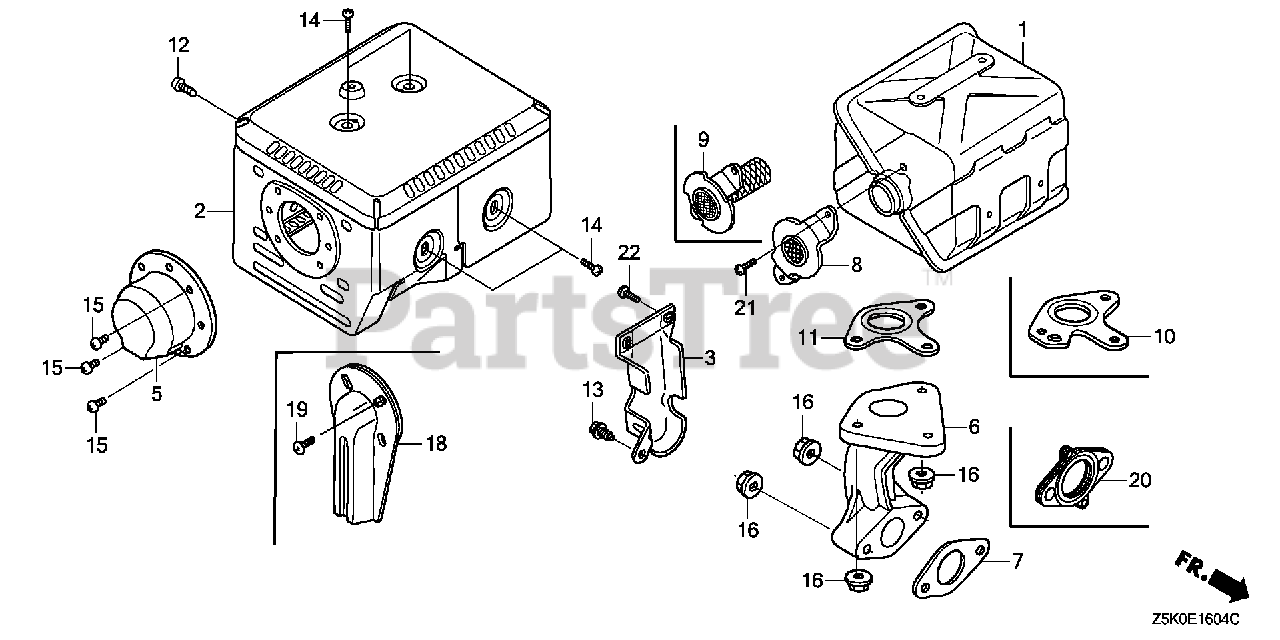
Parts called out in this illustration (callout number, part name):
1	MUFFLER
2	PROTECTOR, MUFFLER
7	GASKET, EX. PIPE
8	FLANGE, BAFFLE
9	ARRESTER, SPARK
10	GASKET, MUFFLER (ARRESTER) (NIPPON LEAKLESS)
10	GASKET, MUFFLER (NIPPON LEAKLESS)
11	GASKET, MUFFLER (THAI LEAKLESS)
12	SCREW, TAPPING (6X10)
14	SCREW, TAPPING (5X8)
16	NUT, FLANGE (8MM)
21	SCREW, TAPPING (5X8)
